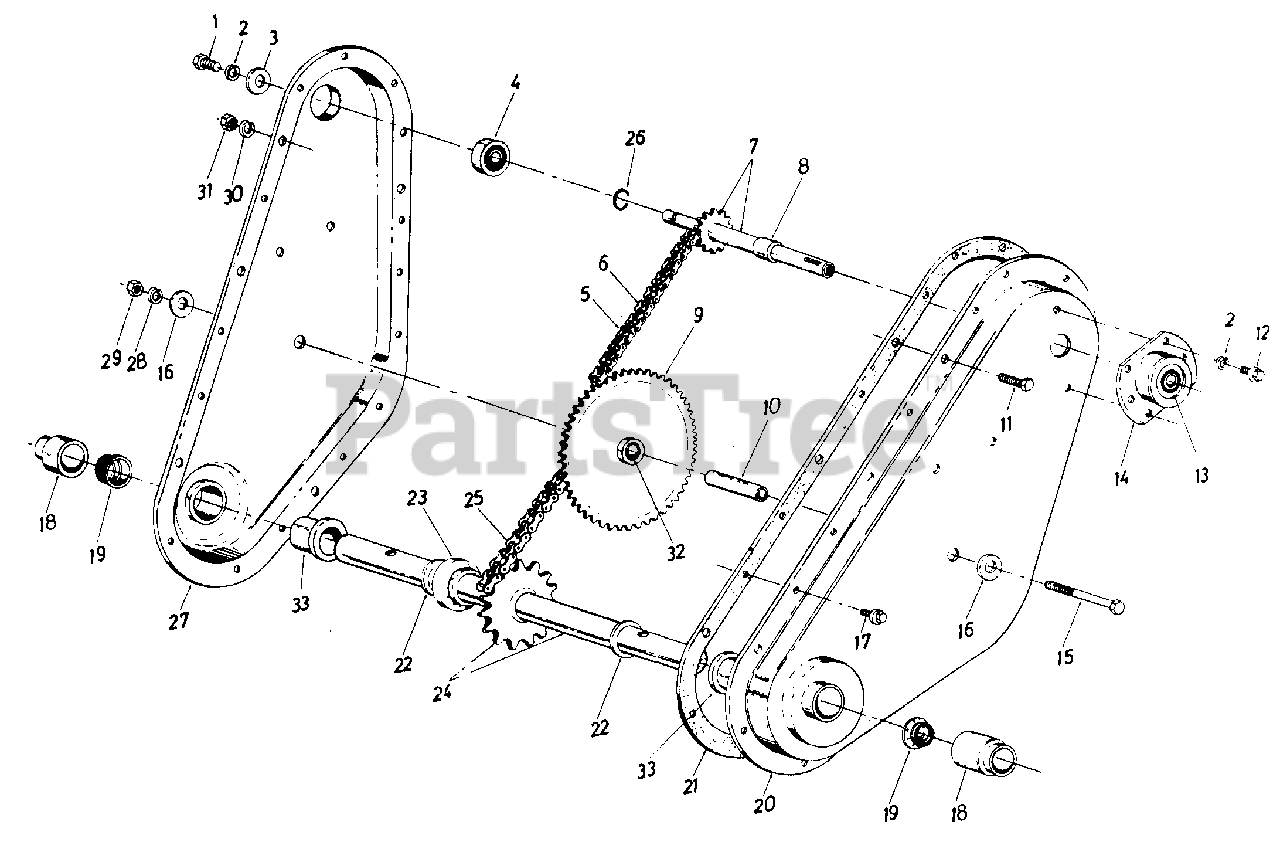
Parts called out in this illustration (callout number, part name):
1	Hex L-Scr. 1/4-28 x .625" Lg.
2	L-Wash. 1/4" I.D.
3	Fl-Wash. 25" I.D. x .93" O.D. x .125" Thk.
4	Bearing .62" I.D. x 1.38" O.D. x .437" Thk.
5	#35 Chain 3/8" Pitch x 52 Links-Endless
6	Master Link
7	Input Shaft Assembly
8	Spacer
9	Sprocket Assembly
10	Sprocket Hub Tubing 3/8" I.D. x 5/8" O.D. x 1.9" Lg.
11	Hex Scr. 5/16-18 x .625" Lg.
12	Hex Wash. Hd. Self-Tap Scr. 1/4-20 x .50" Lg.
13	Bearing .625" I.D. x 1.38" O.D. x .437" Thk.
14	Bearing Housing
15	Hex Scr. 3/8-24 x 2.75" Lg.
16	Fl-Wash. 3/8" I.D. x 1.25" O.D. x .100 Thk.
17	Hex Wash. Hd. Self-Tap Scr. 1/4-20 X .50" Lg.
18	Dust Cap
22	Thrust Wash. 1.00" I.D. x .030" Thk.
23	Step Spacer
24	Tine Shaft Assembly
25	#50 Chain 5/8" Pitch x 46 Links-Endless
26	Snap Ring
29	Hex Nut 3/8-24 Thd.
30	L-Wash. 5/16" Scr.
31	Hex Nut 5/16-18 Thd.
32	Bearing
33	Bearing
14984-0638	HOUSING ASSEMBLY RH BLACK - MTD/TROY-BILT RED (0638)
